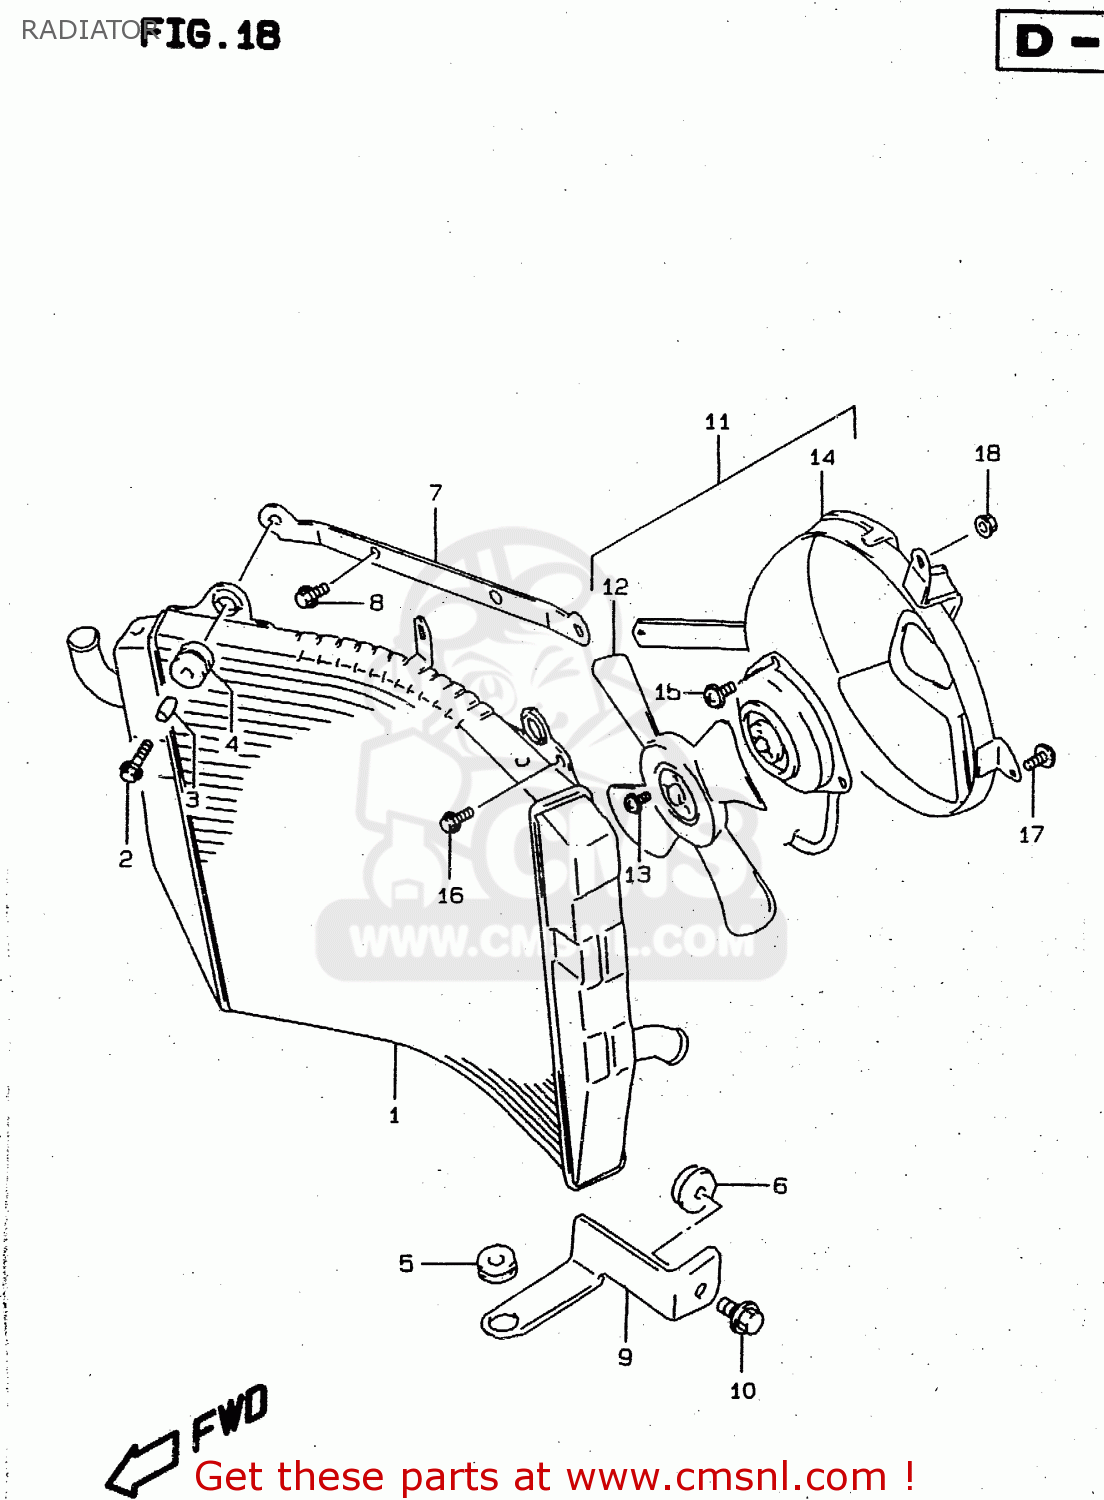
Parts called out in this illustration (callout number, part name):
1	RADIATOR ASSY,WATER
2	BOLT(6X25)
3	SPACER(6.5X10.5X12)
4	CUSHION,RADIATOR LWR
5	CUSHION
6	SPACER,RADIATOR BRACKET LWR
7	BRACKET COMP,RADIATOR
8	BOLT
9	BRACKET COMP,RADIATOR
10	BOLT
11	FAN ASSY,RADIATOR
12	FAN
13	SCREW 4X6
14	SHROUD ASSY,FAN
15	SCREW
16	BOLT
17	BOLT
18	NUT
